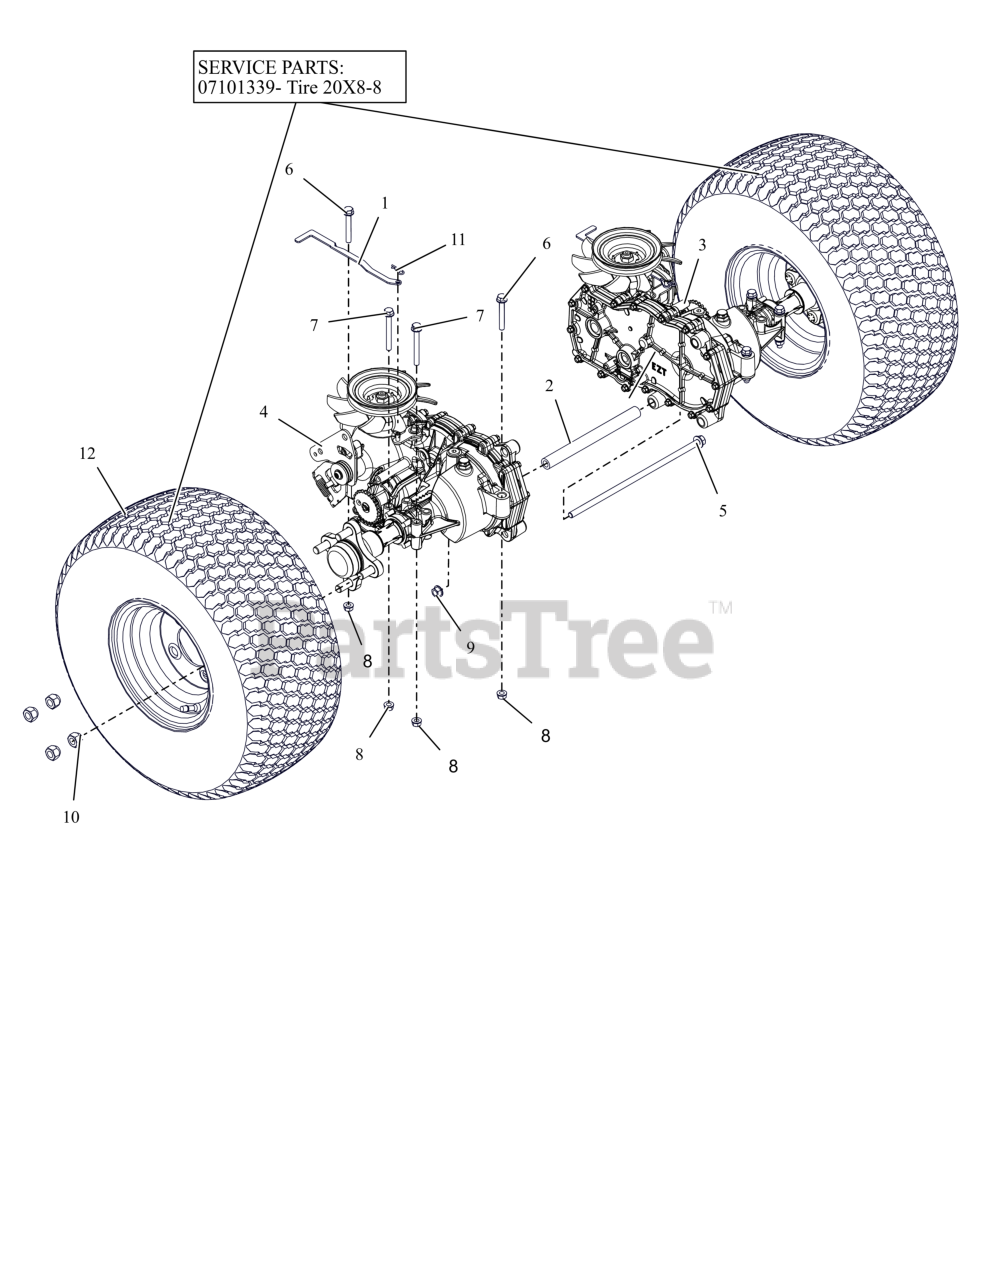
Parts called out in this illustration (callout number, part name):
1	BRKT, DUMP VALVE
2	TUBE, TRANSAXLE BRACE 8.18LG
3	TRANSAXLE
4	TRANSAXLE
5	BLT,HEX-FLG .38-16X11.5 G5 ZCC
6	BLT,HEX-FLG .31-18X2.25 G5 ZCC
7	BLT,HEX-FLG .31-18X2.75 G5 ZCC
8	NUT,LK-CTR-FLG .31-18 GF ZCC
9	NUT-LK-CTR-FLG .375-16 GF ZCC
10	NUT, WHEEL .50-20 ZCC
11	PIN, HAIR #213 .08X1.19 ZCC
12	ASSM TIRE\WHEEL, 20 X 8 -8
12	TIRE, 20 X 8-8
